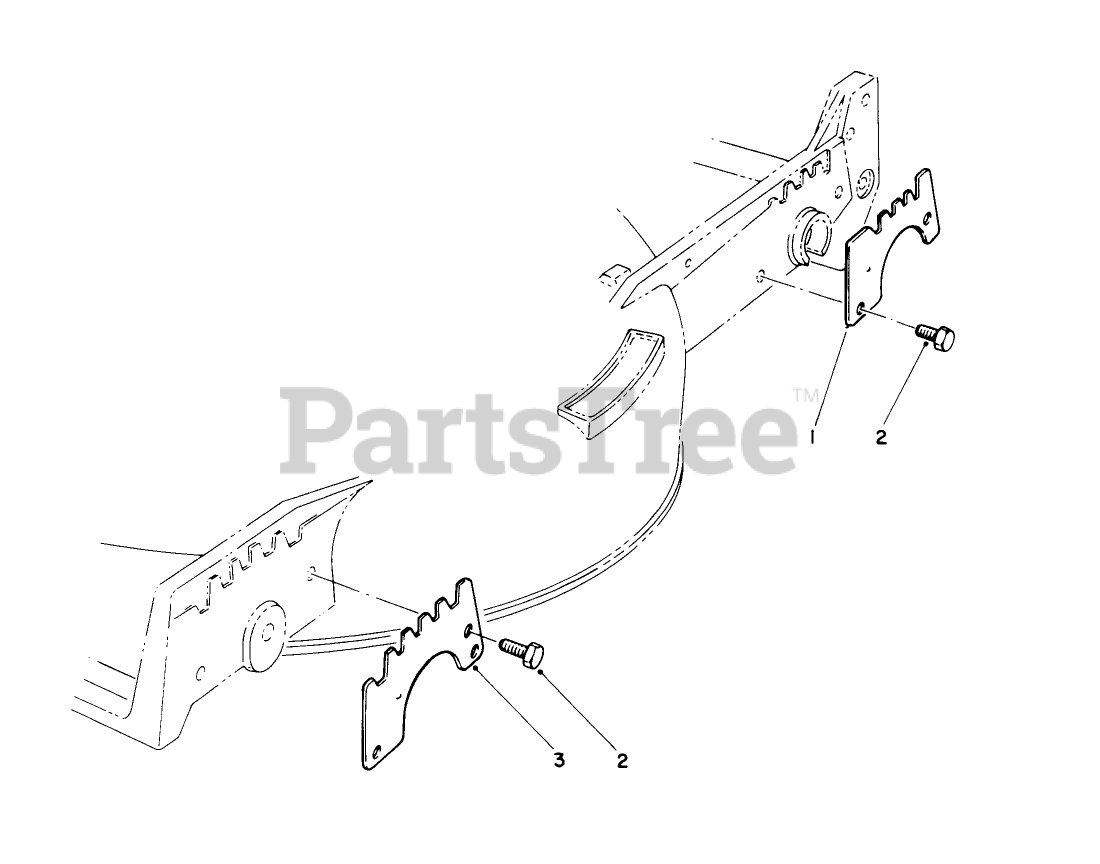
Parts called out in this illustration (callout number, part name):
1	WEAR PLATE,REAR
2	SCREW-HWH
3	WEAR PLATE
